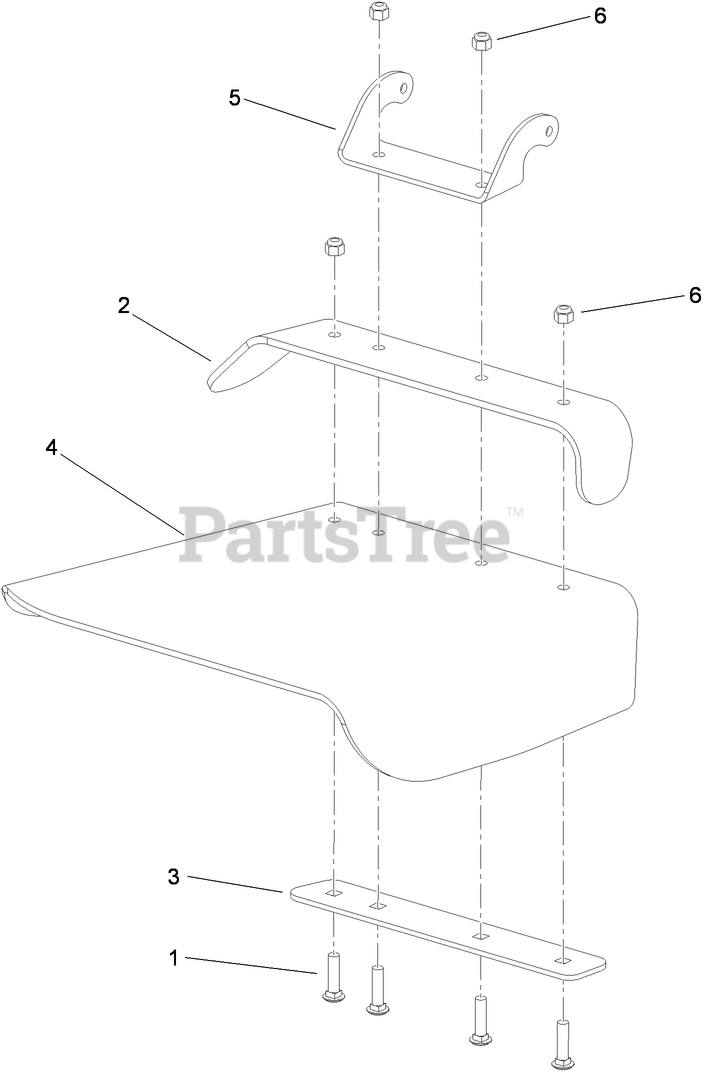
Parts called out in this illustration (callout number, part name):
1	SCREW-CARR
2	DEFLECTOR
3	STRAP-DISCHARGE
4	DEFLECTOR-RUBBER
5	BRACKET-MOUNTING, DEFLECTOR
6	NUT-LOCK, NI
